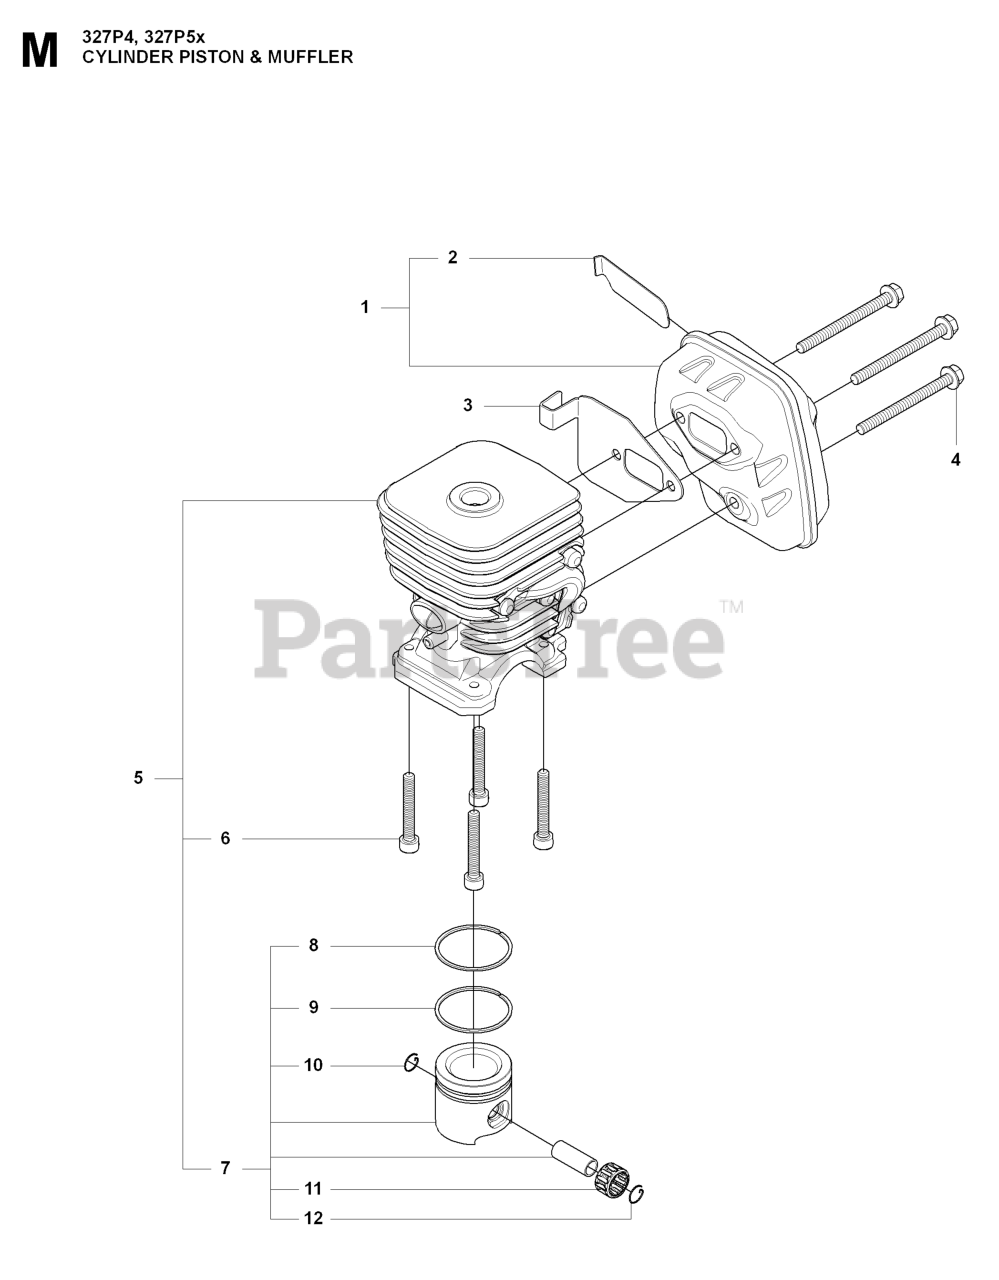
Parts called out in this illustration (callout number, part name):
1	MUFFLER KIT
2	SPARK ARRESTOR SCREEN
5	CYLINDER COMPL
6	SCREW
8	PISTON RING
9	PISTON RING
